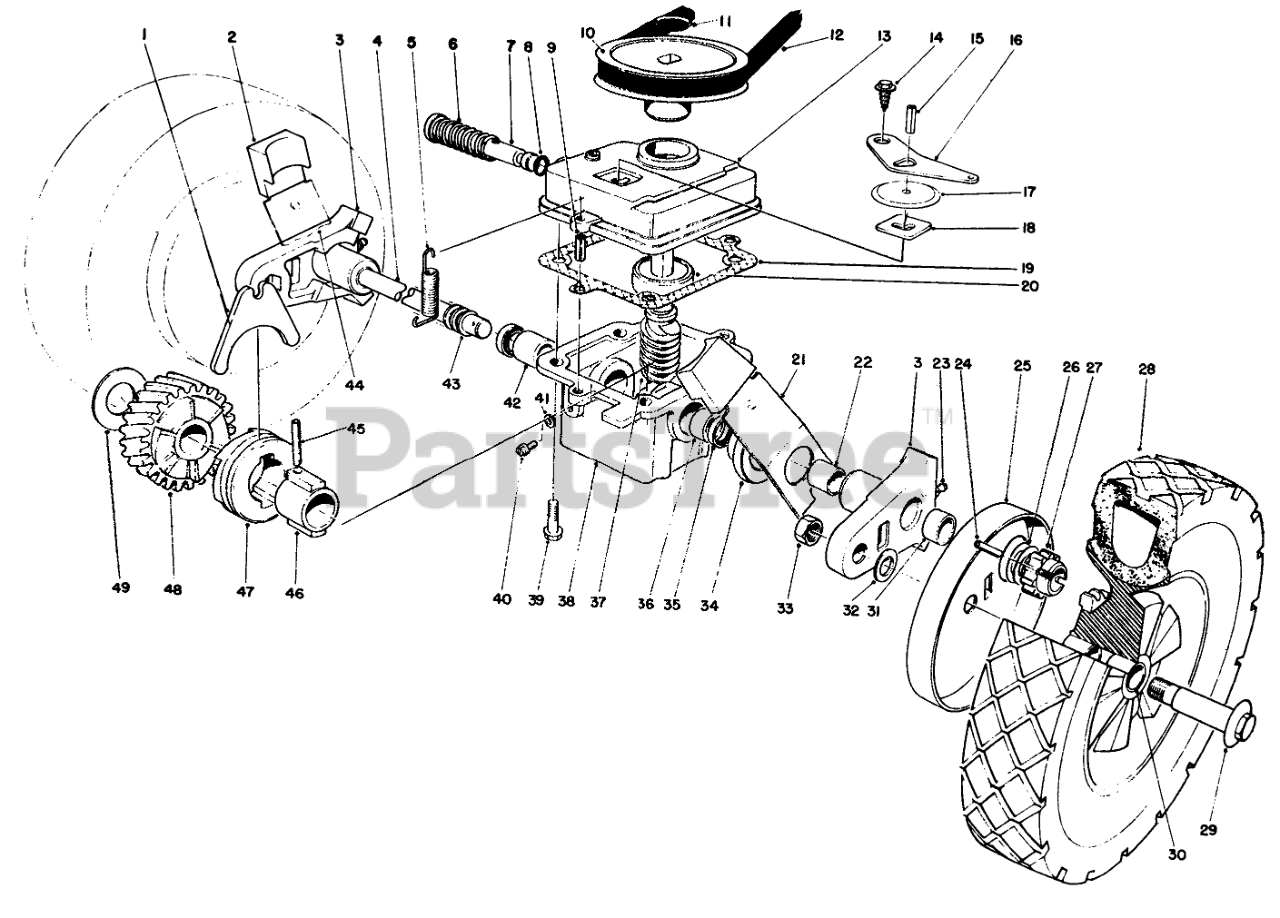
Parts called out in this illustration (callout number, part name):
1	SHIFTER FORK
2	KNOB-ARM
3	Pivot Arm (Incl. Ref. #22, 23&31)
4	DRIVE SHAFT (SERVCE)
5	TENSION SPRING
6	SPRING
7	SHIFTER ROD
8	O-RING
9	3/16 X 1/2 ROLL PIN
10	PULLEY
11	PUSH-ON 93-3236
12	V BELT
13	Case-Upper
14	Screw
15	PIN-ROLL
16	SHIFTER ARM
17	TRANS DUST COVER
18	LATCH PLATE
19	GASKET
20	BEARING
21	SPRING ARM ASM SP LH
22	BUSHING
23	FITTING-GREASE
24	Pin
25	WHEEL COVER
26	THRUST WASHER
27	PINION GEAR 14T
28	Wheel, Tire & Gear Assembly (Incl. Ref. #30)
29	WHEEL BOLT
30	BUSHING
31	BUSHING
32	WASHER
33	NUT-LOCK
34	CAP-END
35	SEAL-OIL
36	BUSHING
37	Worm Shaft & Gear (Incl. Ref. #48)
38	Gear Case (Incl. Ref. #35-36 & 42)
39	Screw
40	NYLON SCREW
41	FILL PLUG GASKET
42	BUSHING
43	COVER-SHAFT, DRIVE
44	Spring Arm Assembly R.H.
45	COIL PIN
46	SLEEVE
47	CLUTCH JAW
48	Helical Gear
49	THRUST WASHER
